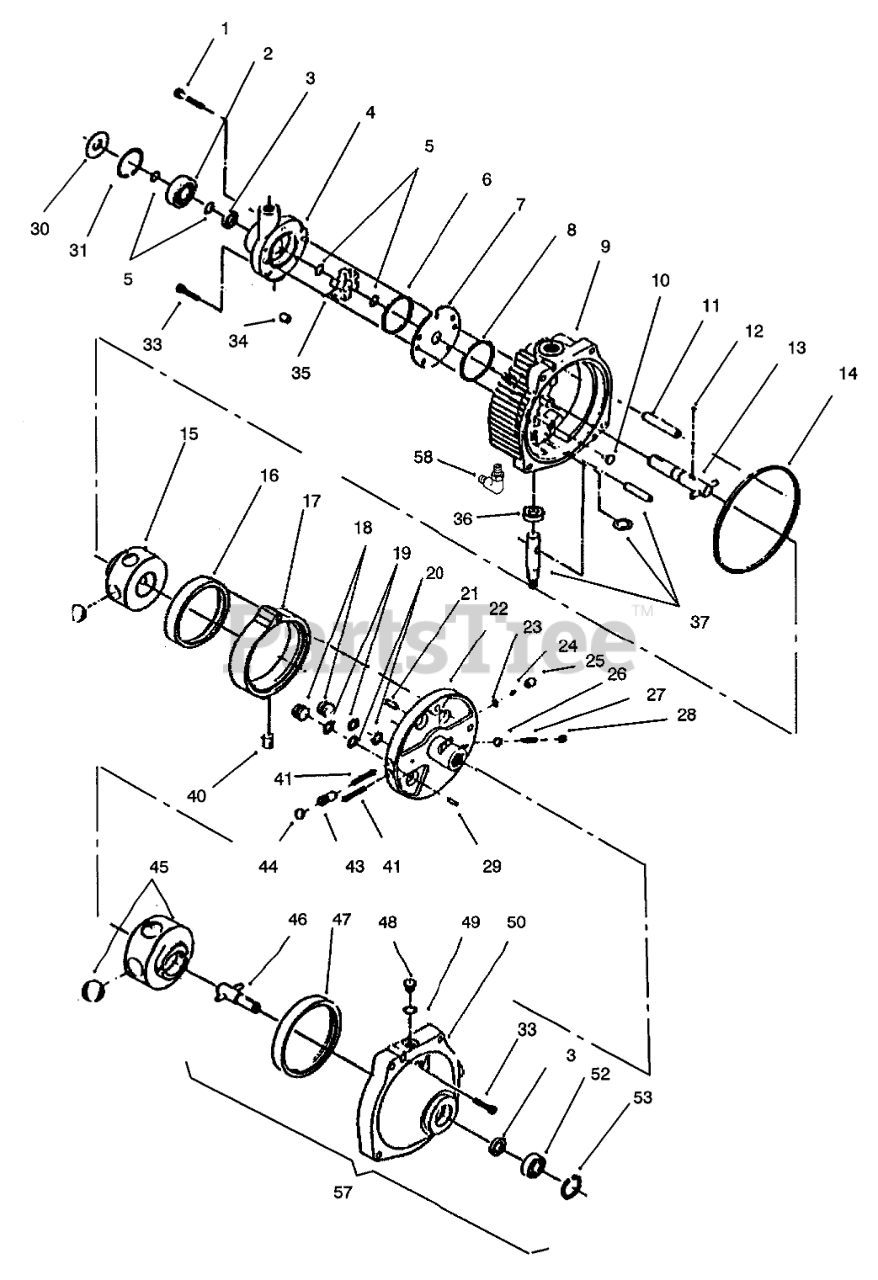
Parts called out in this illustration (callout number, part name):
1	CAPSCREW
2	BEARING
3	SEAL-OIL
4	PUMP-CHARGE
7	PLATE
9	COVER SUB ASM
10	BUTTON
13	SHAFT
15	ROTOR
16	PUMP-RACE
17	RING-CAM
18	PISTON
20	O-RING
22	PINTLE
27	SPRING
30	SHIELD-GRASS
31	RETAINING-RING
33	SCREW-HH
35	CARRIER
36	SEAL-OIL
37	SHAFT KIT
40	INSERT
41	SPRING
45	ROTOR
46	SHAFT
48	PLUG ASM
49	O-RING
52	Bearing
55	SEAL KIT
56	CAM RING ASM
57	ASM-Body
58	FITTING-HYDRAULIC 90 DEG
